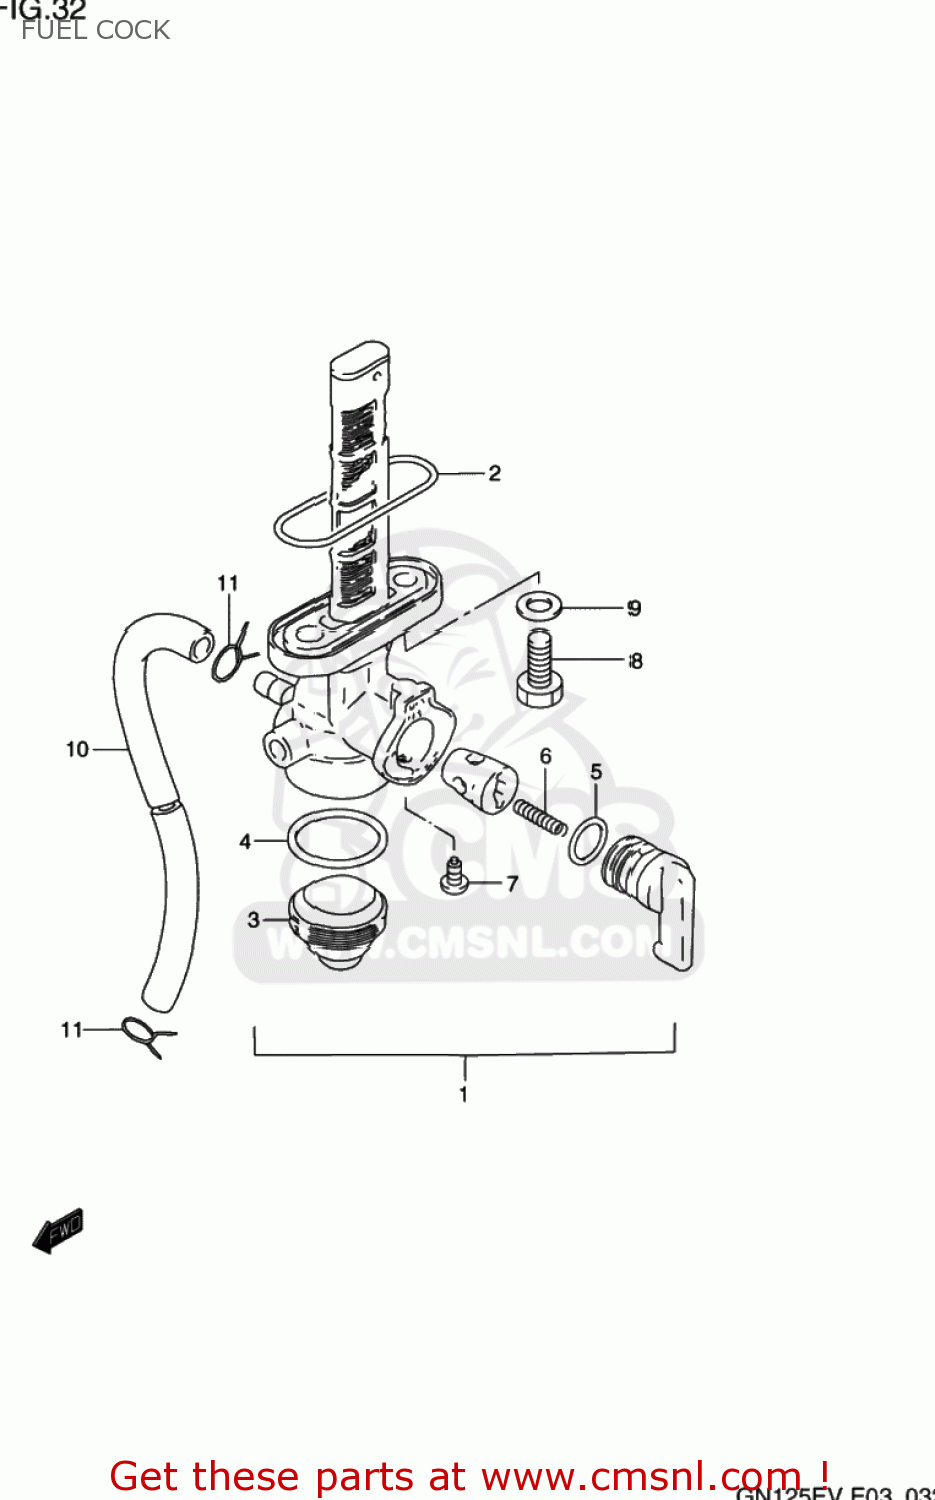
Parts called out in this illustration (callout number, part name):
1	COCK ASSEMBLY,FUEL
2	O RING,FUEL COCK
3	CUP,STRAINER
4	GASKET,FILTER (NAS)
5	O RING,LEVER
6	SPRING
7	SCREW
8	BOLT(6X20)
9	GASKET(6.4X11.5X0.8) (NAS)
10	HOSE(5X8.2X600)
11	CLIP
